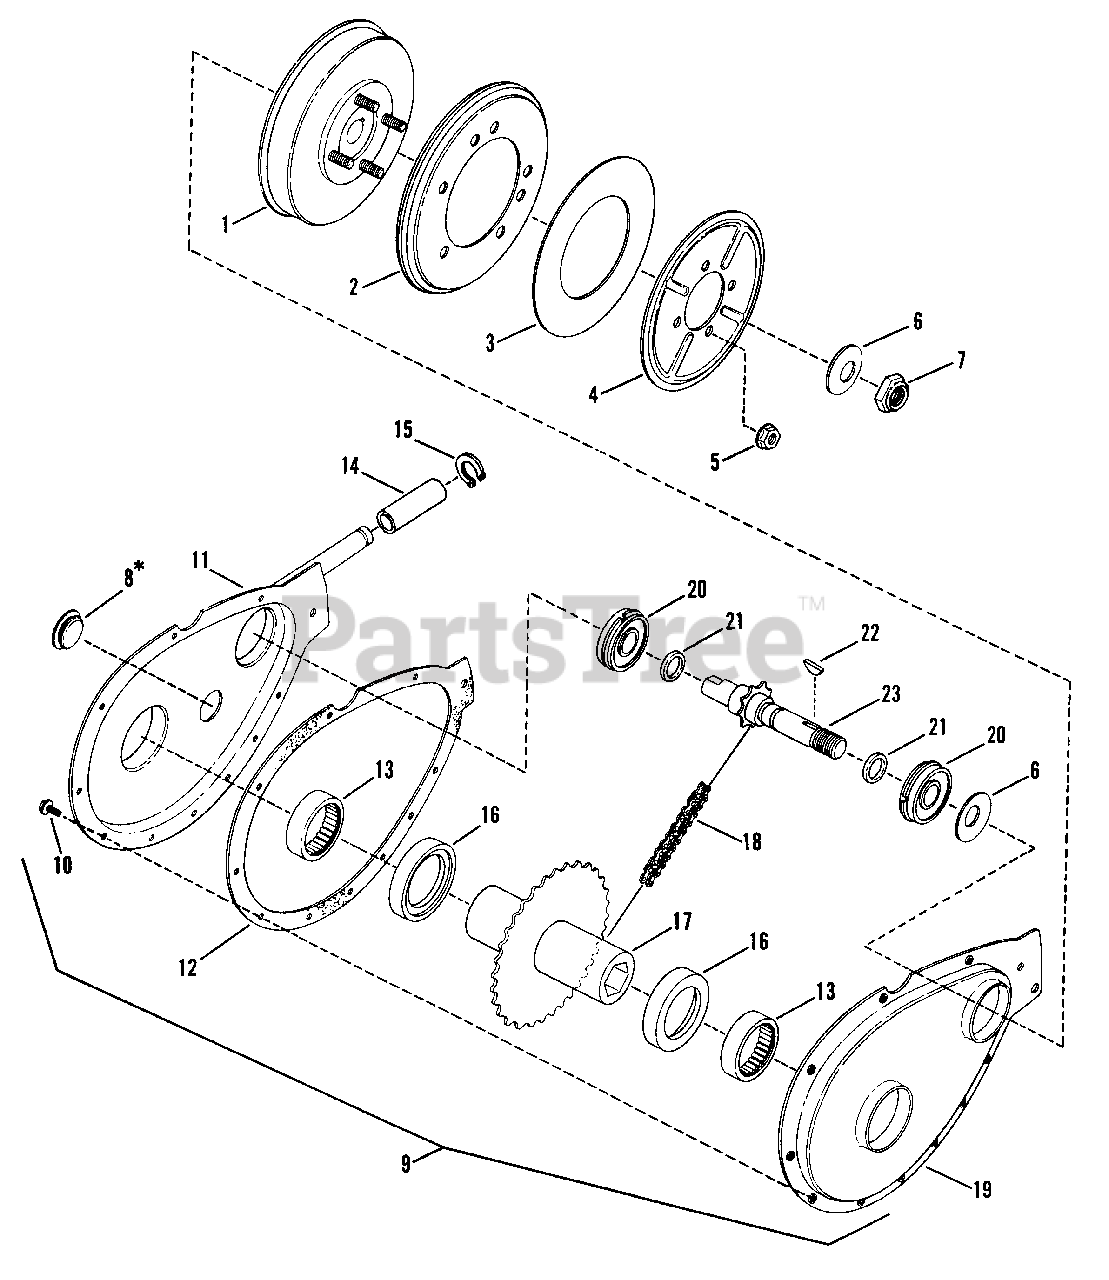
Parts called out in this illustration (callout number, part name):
1	HUB, Driven Disc
2	DISC, Driven
3	WASHER, Thrust
4	PLATE
5	NUT, 5/16-18 Hex Flange Lock
6	WASHER, Belleville
7	NUT, 5/8-18 Hex Lock
8	PLUG, Oil Fill & Check
9	ASSEMBLY, Chain Case
10	SCREW, #10-24 x 1/2" Hex Washer Self-Tap (Torx)
11	CASE, Sprocket
12	GASKET, Case Cover
13	BEARING, Needle
14	ROLLER
15	RING, Retaining
16	WASHER, Nylon Thrust
17	HUB & SPROCKET
18	CHAIN
19	COVER, Chain Case
20	BEARING, Ball
21	"O" RING
22	KEY, 1/8 x 5/8" Woodruff
23	SPROCKET & SHAFT
